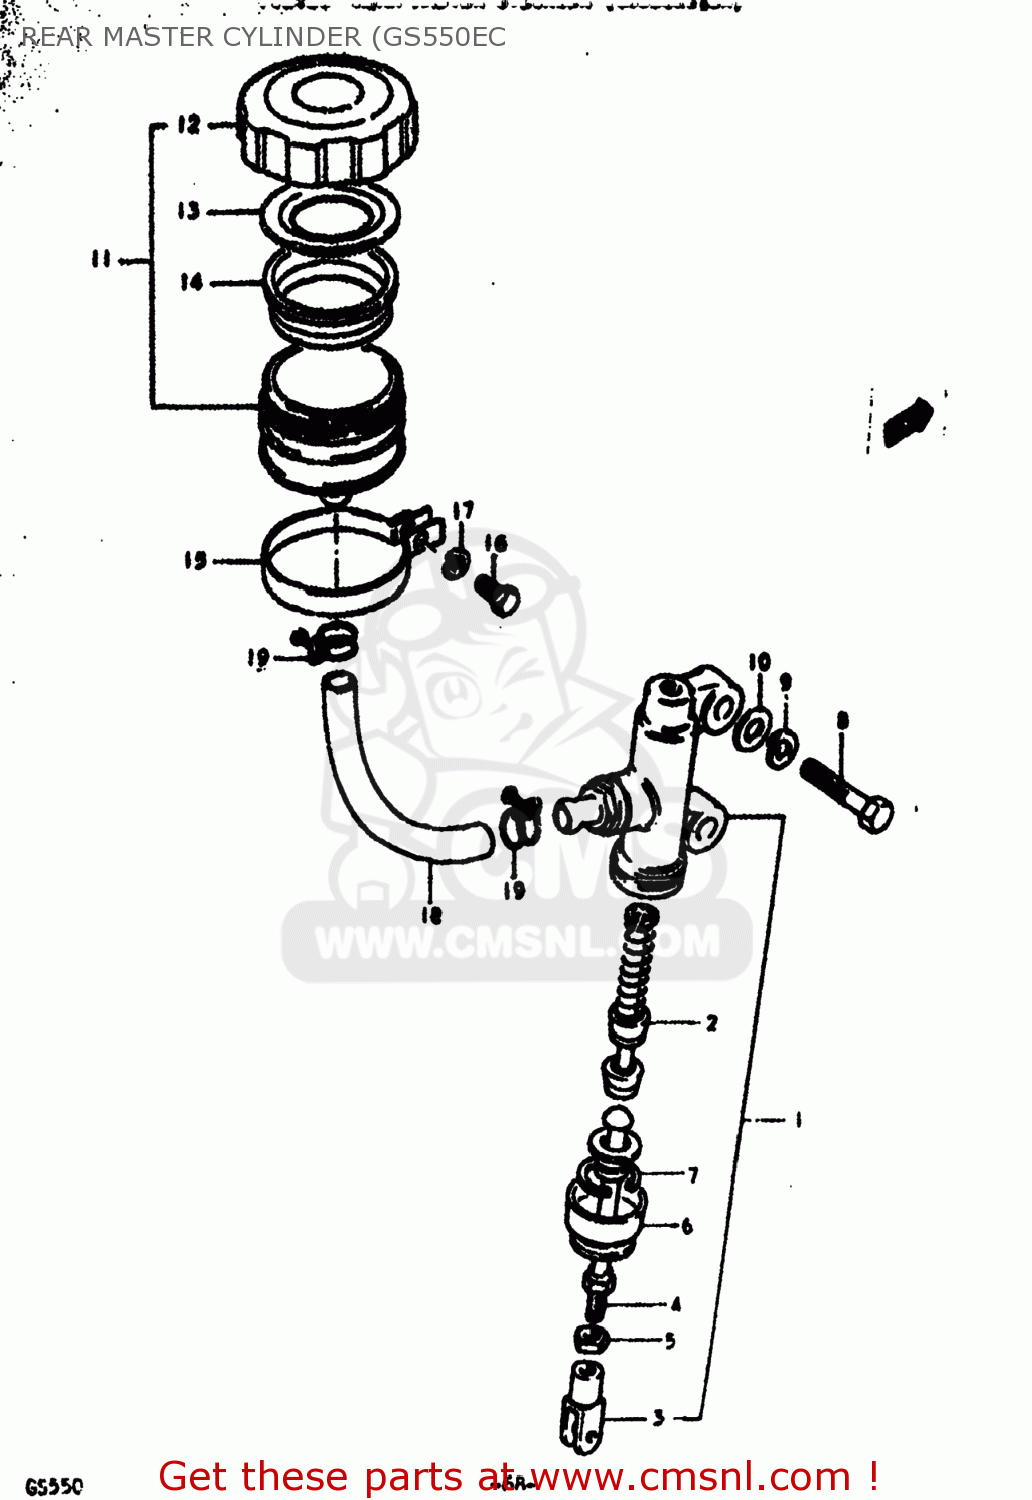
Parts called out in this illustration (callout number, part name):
1	CYLINDER ASSEMBLY,REAR MASTER
2	PISTON/CUP SET
3	YOKE
4	ROD,PUSH
5	NUT
6	BOOT
7	CIRCLIP
8	BOLT
9	LOCK WASHER
10	WASHER
11	TANK ASSEMBLY,RESERVOIR
12	CAP
13	PLATE,DIAPHRAGM
14	DIAPHRAGM
15	CLAMP
16	BOLT, UPPER
17	LOCK WASHER
18	HOSE,RESERVOIR TANK
19	CLAMP
